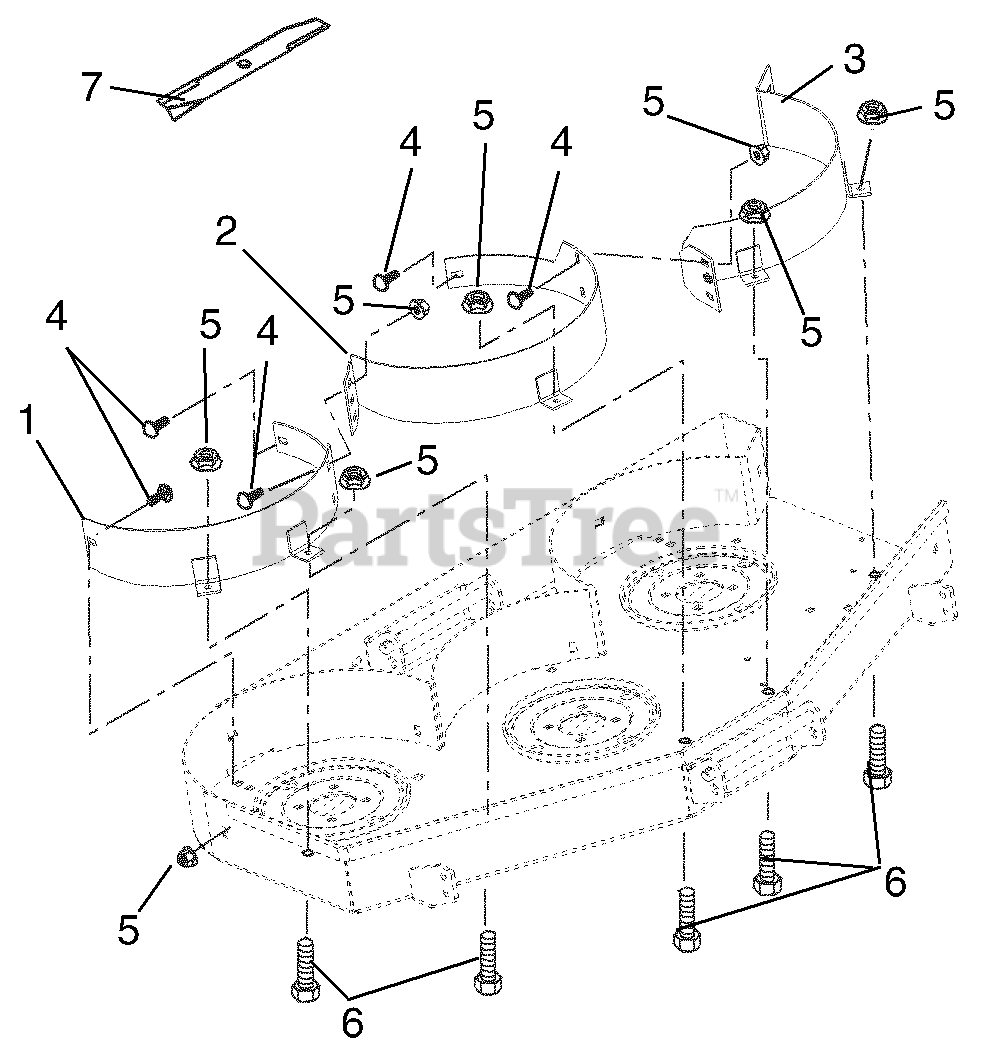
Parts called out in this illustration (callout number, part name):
1	BAFFLE-MULCH-LEFT FRONT-40"
1	BAFFLE-MULCH-LEFT FRONT-44"
1	BAFFLE-MULCH-LEFT FRONT-48"
1	BAFFLE-MULCH-LEFT FRONT-52"
2	BAFFLE-MULCH-CENTER FRONT-40"
2	BAFFLE-MULCH-CENTER FRONT-44"
2	BAFFLE-MULCH-CENTER FRONT-48"
2	BAFFLE-MULCH-CENTER FRONT-52"
3	BAFFLE-MULCH-RIGHT FRONT-40"
3	BAFFLE-MULCH-RIGHT FRONT-44"
3	BAFFLE-MULCH-RIGHT FRONT-48"
3	BAFFLE-MULCH-RIGHT FRONT-52"
4	BLT-RDHDSQSHNK .31-18X.62 BKZC
5	NUT-LK-TOP-FLG .31-18 BLKZC
6	BLT SERHFWH .31-18X.62 GR5BKZC
7	BLADE-40" MULCHING (13.83)
7	BLADE-44" MULCHING (15.5)
7	BLADE - MULCHING (16.25)
7	BLADE - MULCHING (18.00")
